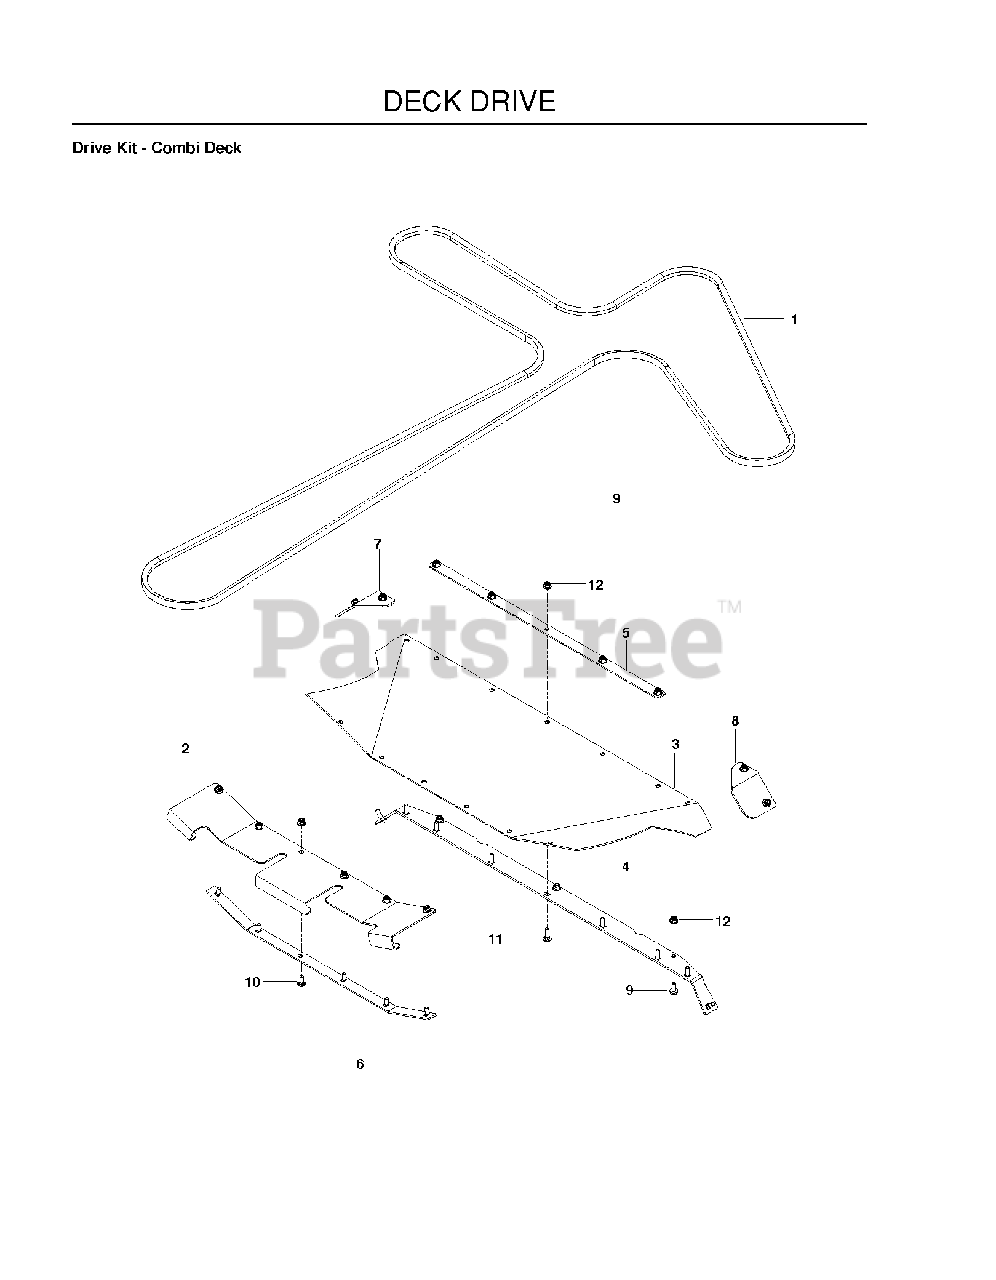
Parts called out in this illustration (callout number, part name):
1	BELT, DECK
2	BRACKET, REAR MOUNT, BLK
3	GUARD, DEBRIS
4	PLATE, MTG BLACK
5	STRAP, LONG BLACK
6	STRAP, MOUNT, BLK
7	BRACKET, LT BLK
8	BRACKET, RT, BLK
9	HHFS 5/16-18 X 3/4
10	BOLT 5/16C X 3/4" CARRIAGE
11	RHSNB 5/16C X 1
12	5/16-18 NYLOC FLANGE NUT
